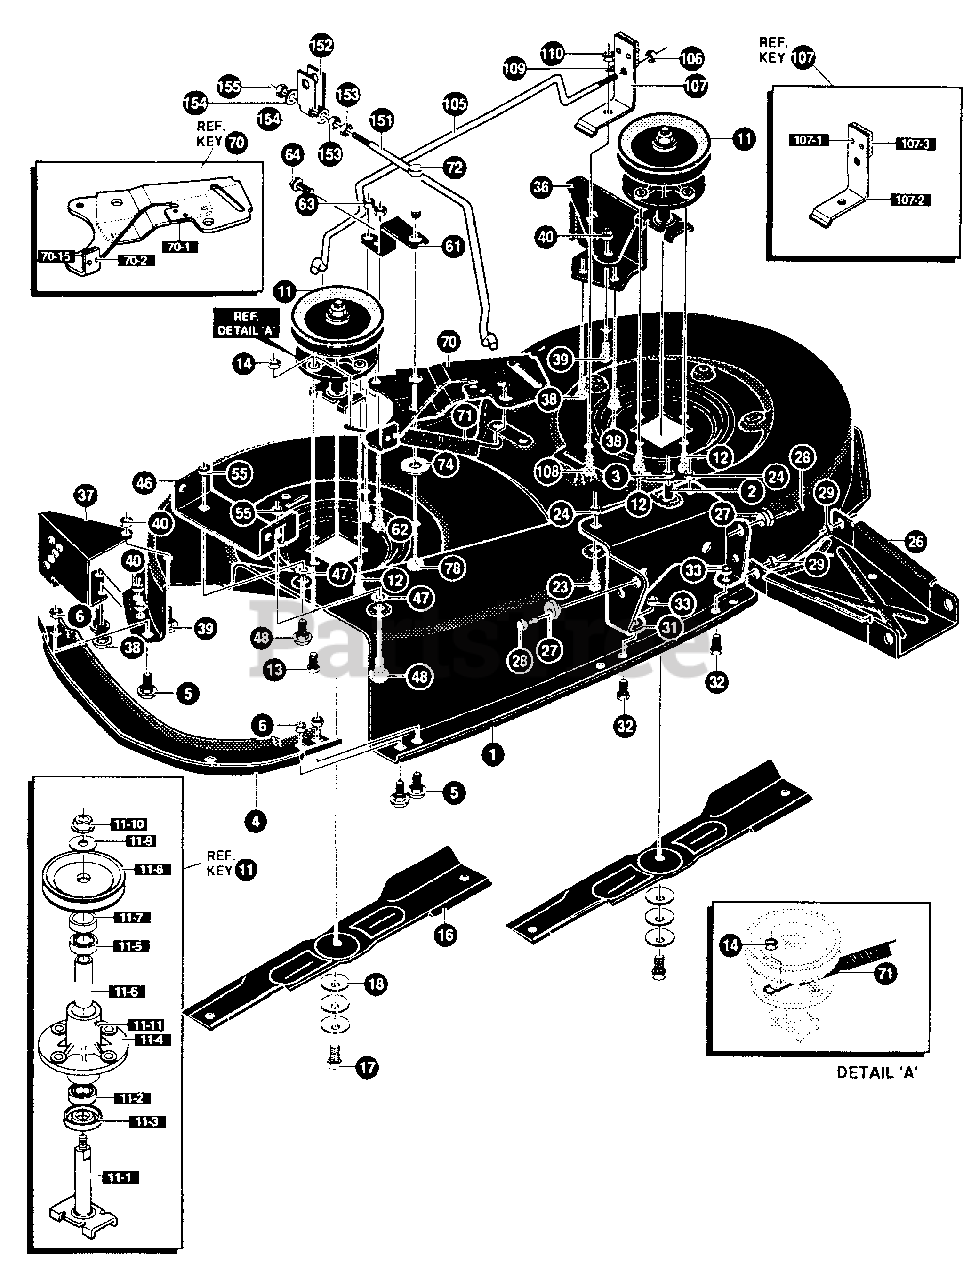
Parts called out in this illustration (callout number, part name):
1	40 DECK KIT
2	SCREW, 5/16-18X .75 HHC
3	NUT, 5/16-18 REGHEXCTRLK
4	TOE GUARD - MULCHER
5	BOLT, 5/16-18X 5/16-18X.63 CARR
6	NUT, 5/16-18 REGHEXCTRLK
11	QUILL 36/39/40/43 W/ZERKS
11-1	SHAFT/SADDLE 36"
11-2	BRNG. BALL 6203-A-C3 (SEAL)
11-3	DUST SHIELD
11-4	QUILL HSG. EXP
11-5	BRNG, BALL 6203-2AA(SEALS)-C3
11-6	SPACER, SLEV .669X .88X3.797
11-7	SPACER, SLEV .672X .93X .438PM
11-8	PULLEY, 26/36" QUILL V5L
11-9	WASHER, SPECIAL QUILL
11-10	NUT, 7/16-20 WDFLLK
11-11	ZERK, GREASE FITTING
12	SCREW, 5/16-18X .75 WAHHTAP
13	SCREW, 5/16-18X1.38 WAHHTAP
14	NUT, 5/16-18 REGHEXCTRLK
16	BLADE, 40' STD-LIFT 20.32
17	SCREW, 3/8-24X1.00 NYLHHC
18	WASHER,.391DX1.25DX.07 BELLVIL
23	BOLT. 5/16-18X 5/16-18X.63 CARR
24	NUT, 5/16-18 REGHEXCTRLK
26	CHANNEL DRAWBAR 40 EURO
27	NUT, ADJUST
28	SCREW, 5/16-18X1.00 HHC
29	NUT, 5/16-18 REGHEXCTRLK
31	BRACKET FRT
32	SCREW. 5/16-18X .75 HHC
33	NUT, 5/16-18 REGHEXCTRLK
36	BRACKET,GAGE WHEEL L.H.
37	BRACKET, GUAGE WHEEL RH
38	SCREW, 5/16-18X .75 HHC
39	BOLT. 5/16-18X 5/16-18X.63 CARR
40	NUT, 5/16-18 REGHEXCTRLK
46	BRACKET CHUTE MOUNT
47	WASHER. FLAT .469X .92X.065
48	BOLT, 5/16-18X .63 CARR
55	NUT, 5/16-18 REGHEXCTRLK
61	BRACE IDLER SUPPORT 40" 43"
62	SCREW. 5/16-18X .75 HHC
63	NUT, 5/16-18 HWDFLCTRLK
64	SCREW, 1/4-20X1.25 HHWATAP
70	IDLER ARM ASSEMBLY
70-1	ARM IDLER 40/43"DECK
70-2	RIVET, OVSET .187DIAX .50LG ST
70-3	BRAKE PAD - HARD - 232AF
71	SPRING.071 X .62 X 4.37
72	BOLT. 500X2.15 HHSH
74	WASHER FLAT .391X1.00X.209
78	NUT, 3/8-16 HWDFLLK MACK
105	ROD BRAKE
106	NUT 1/4-20 REGHEXCTRLK
107	BLADE BRAKE ASSY
107-1	RIVET, TRSET .185DIAX .41 LG ST
107-2	BRAKE ARM
107-3	BRAKE PAD - HARD - 232AF
108	SCREW, 5/16-18X .75 HHC
109	WASHER, FLAT .344X .69X.065
110	NUT, 5/16-18 REGHEXCTRLK
151	ROD, CLUTCH
152	CLEVIS, EURO
153	NUT, 5/16-18 REGHEX
154	WASHER, FLAT .344X .69X.065
155	NUT, 5/16-18 REGHEXCTRLK
156	TIE CABLE BLACK NYLON 5.62L
